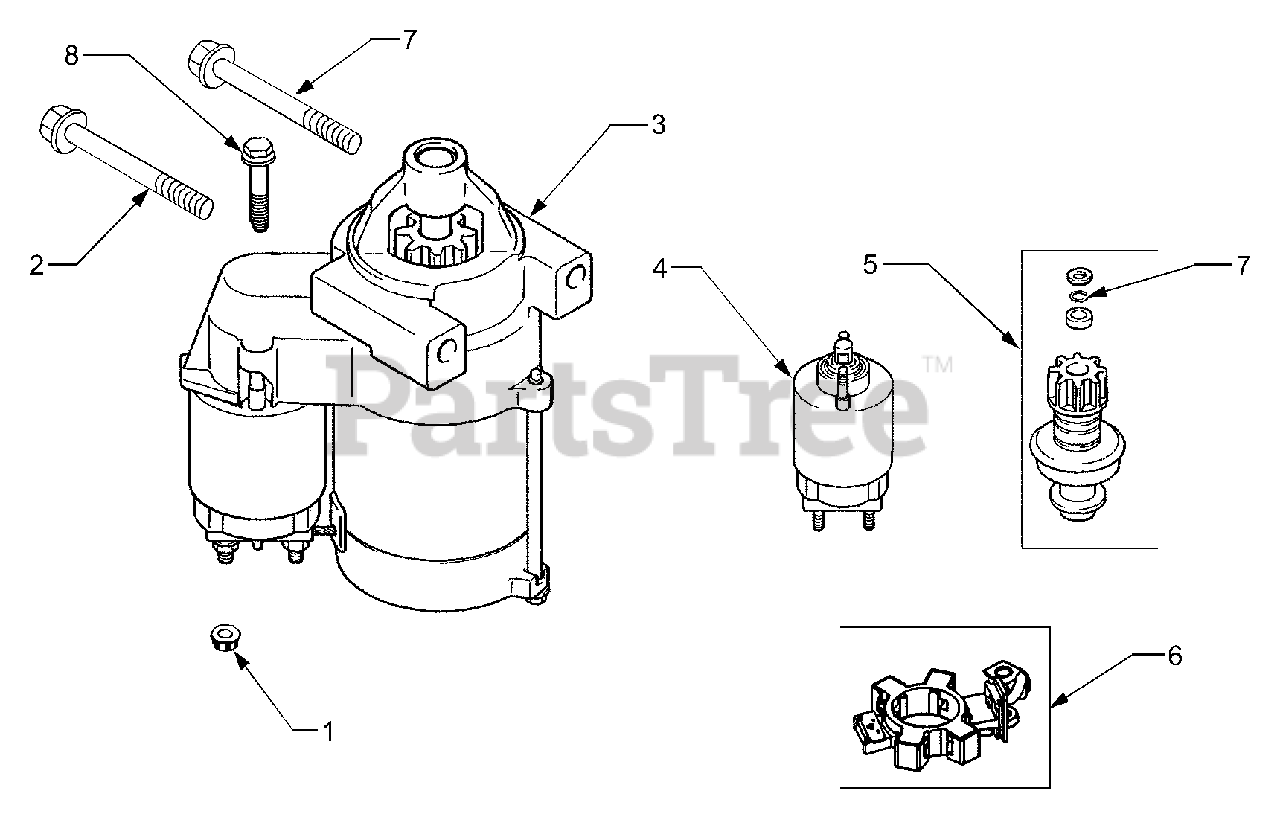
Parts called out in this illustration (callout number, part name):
1	Nut, Hex Flange M8 x 1.25"
2	Screw, Hex Flange M8 x 1.25 x 80
3	Starter, Solenoid Shift Assembly
4	Kit, Solenoid
5	Kit, Pinion Drive
7	Ring, Retainer
8	Screw, External Torx Hd.
